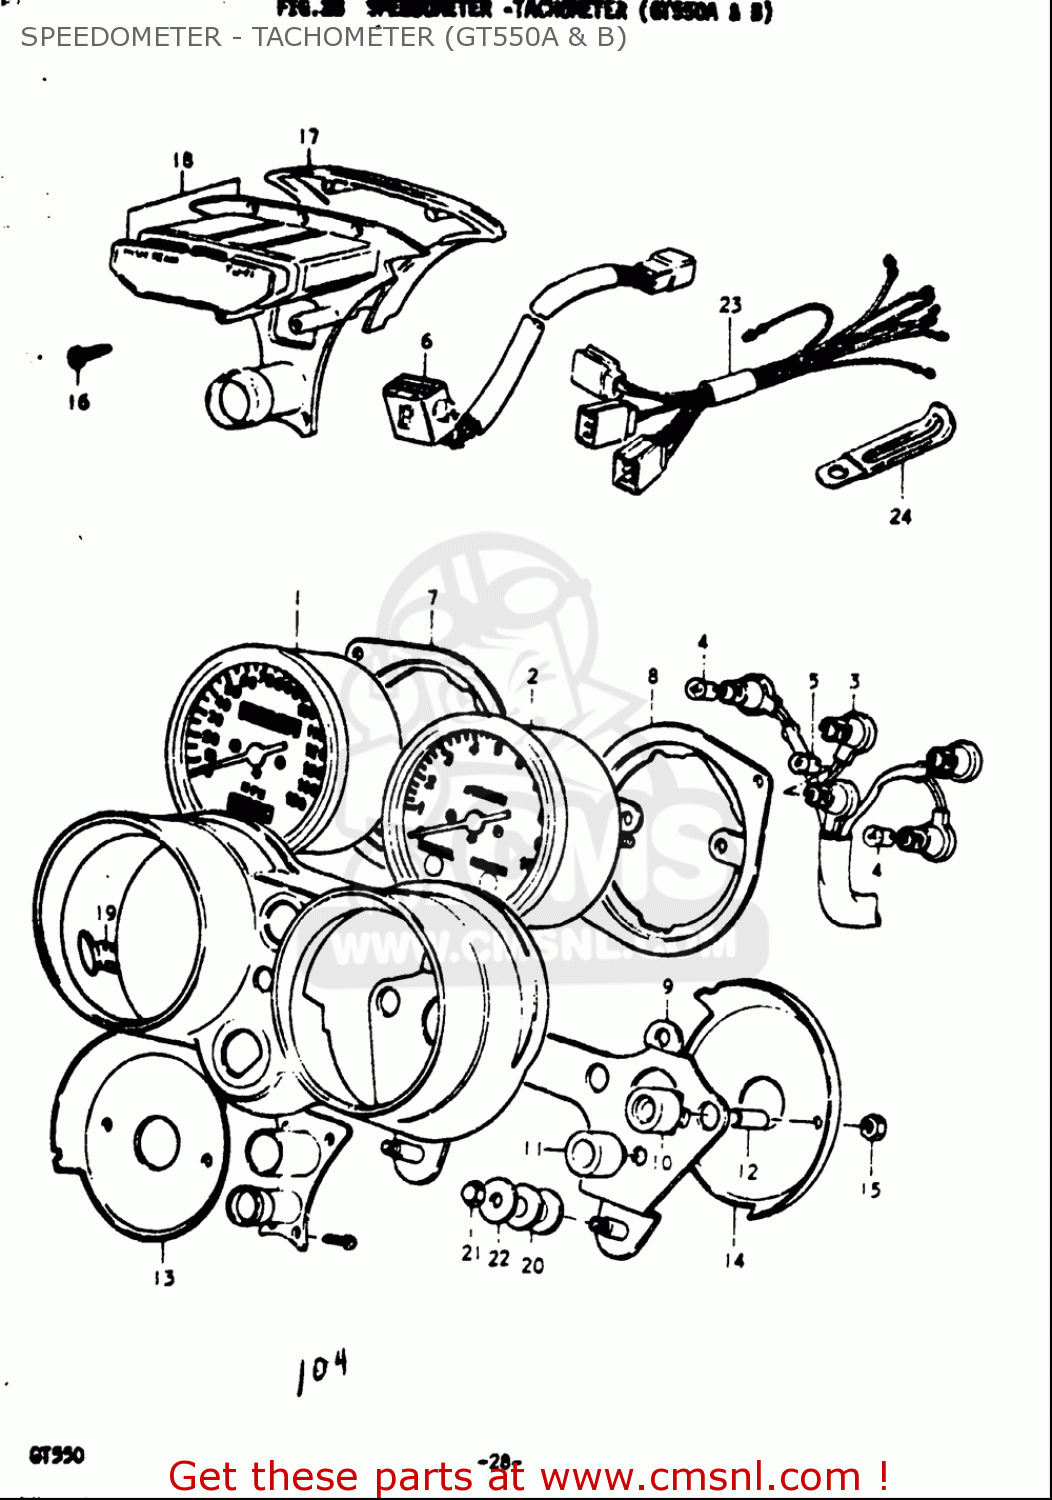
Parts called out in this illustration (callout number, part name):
4	BULB(12V3.4W,STANLEY,A72A)
5	BULB(12V1.7W,A71A)
7	BRACKET,SPEEDOMETER
8	PLATE,TACHOMETER
10	CUSHION,METER NO.1
11	CUSHION,METER
15	NUT
16	SCREW
20	CUSHION
22	WASHER(6.5X18X1.6)
24	CLAMP(L:65)
